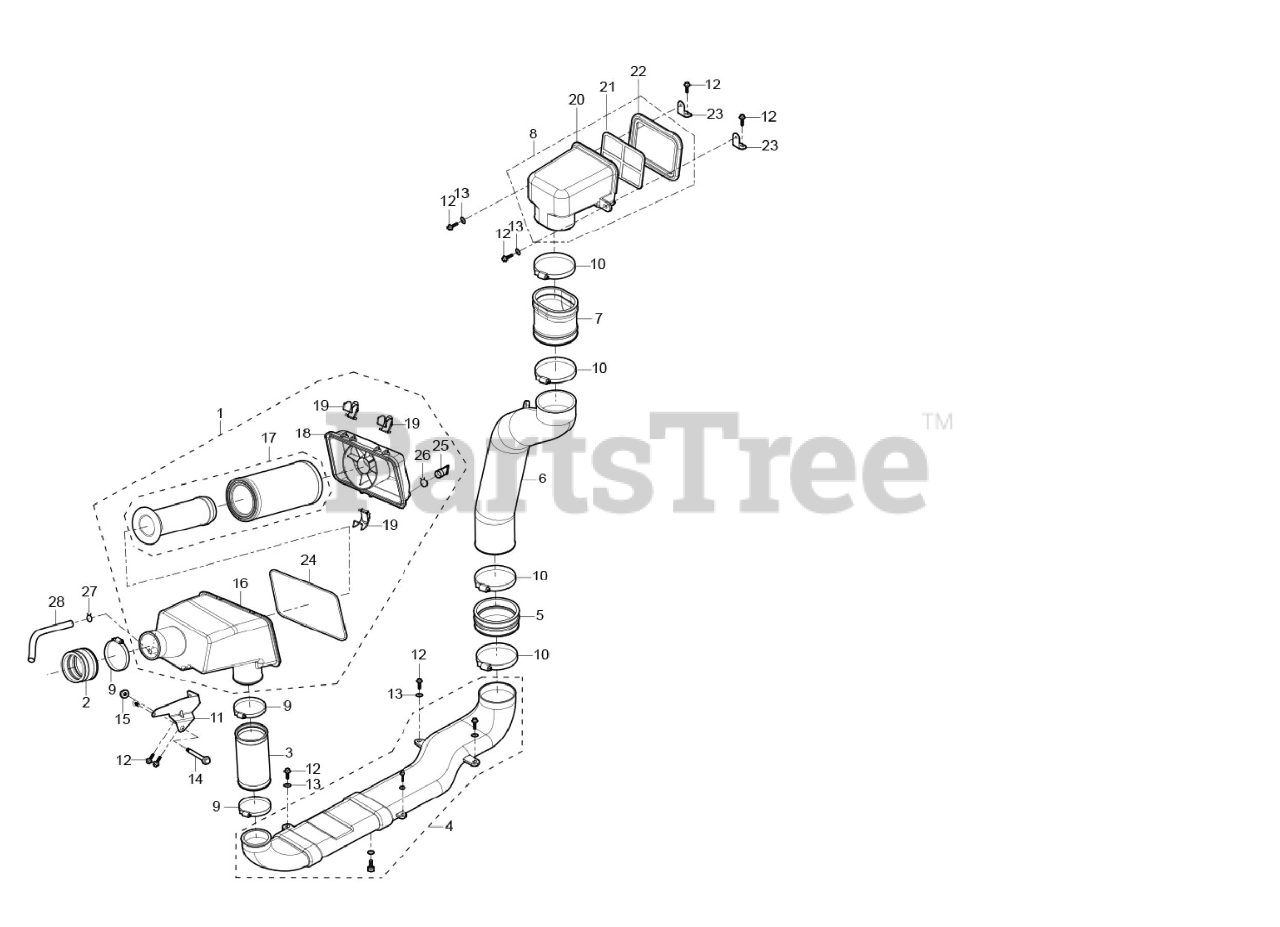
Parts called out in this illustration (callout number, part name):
1	Air cleaner second assembly
2	INNER THROTTLE SLEEVE
3	AIR CLEANER SLEEVE - INNER
4	AIR CLEANER DUCT - INNER
5	AIR CLEANER SLEEVE - INNER
6	AIR CLEANER DUCT - INNER
7	AIR CLEANER SLEEVE - INNER
8	Air cleaner first assembly
9	Screw Hoop J
10	NARROW BAND CLAMP
11	AIR CLEANER STRAP - PLATED
12	Hexagon Flange Bolt M6x16
13	WASHER - FLAT
14	Hexagon Flange BoltM10x1.25x55
15	LOCK NUT M10x1.25
16	SECONDARY AIR BOx
17	SECONDARY AIR FILTER
18	AIRBOx COVER
20	PRIMARY FILTER BODY
21	PRIMARY AIR FILTER
22	PRIMARY AIR FILTER COVER
24	SECONDARY FILTER SEAL
27	Spring Clamp E
